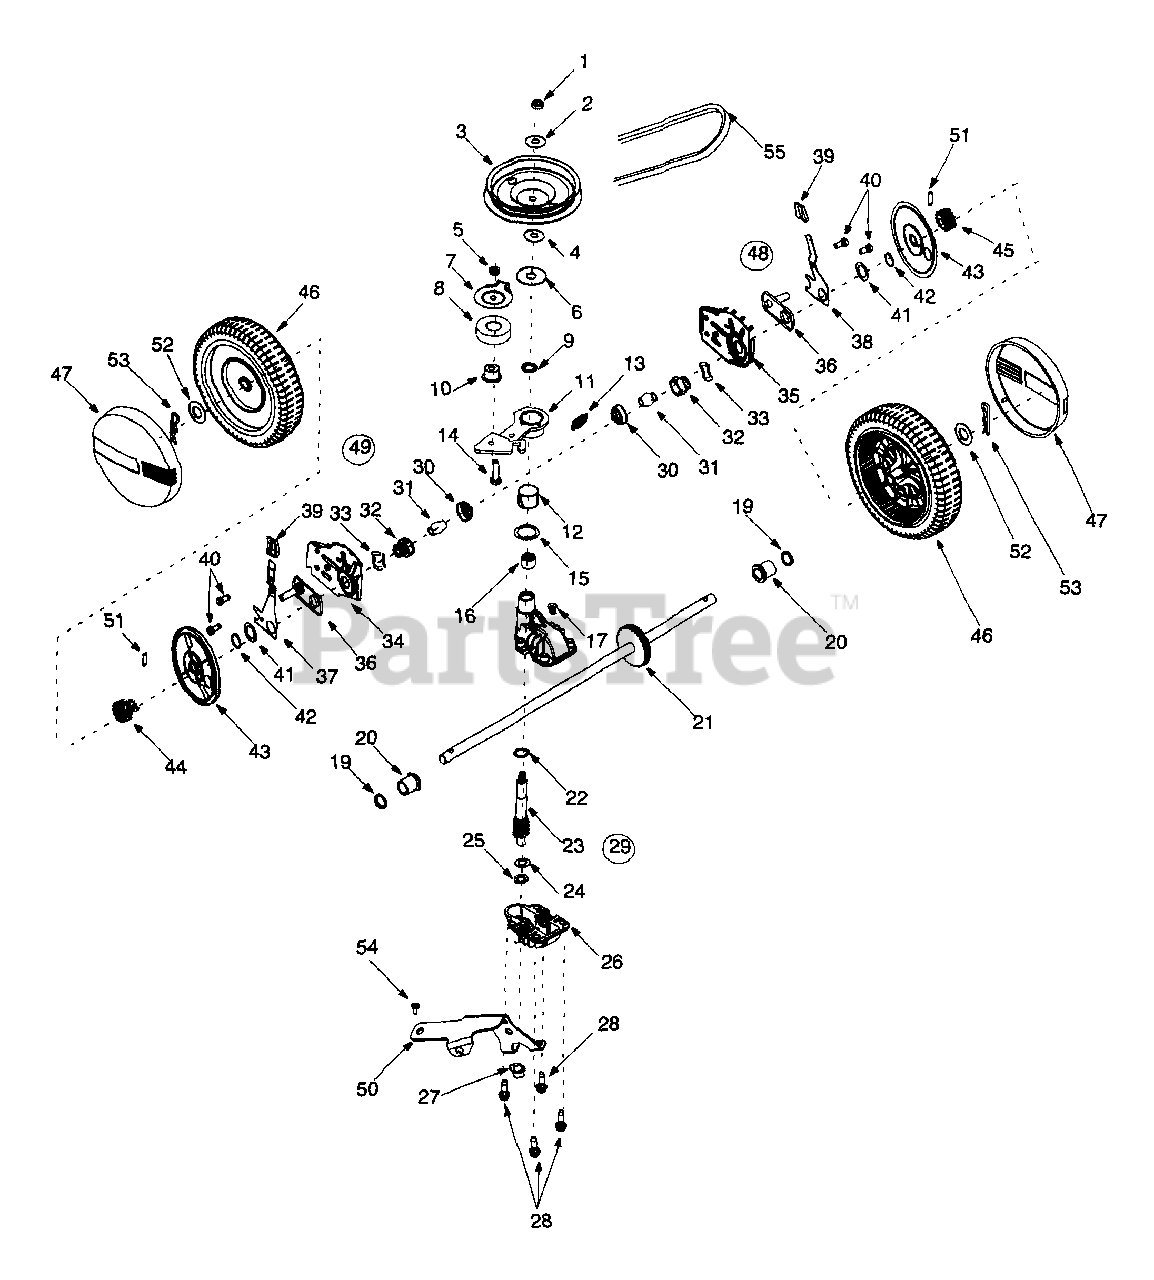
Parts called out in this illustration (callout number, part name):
1	Hex Jam Nut 5/16-24
2	Bell Washer .325 x .930 x .045
3	Pulley, 3.82 x .313 x .68
4	Bell Washer .325 x .930 x .045
5	Lock Nut 1/4-28
6	Flat Washer .442 x 1.38 x .060
7	Belt Keeper
8	Ball Bearing
9	Oil Seal
10	Flange Spacer
11	Idler Bracket Assembly
12	Bearing Sleeve
13	Flat Washer .504 x .700 x .030
14	Hex Cap Screw 1/4-28 x 1.00
15	Flat Washer .865 x 1.145 x .030
16	Needle Bearing .438 x .625 x .500
17	Plug 1/4 x .437
19	Oil Seal .500 x .687 x .094
20	Flange Bearing
21	Output Shaft
22	Flat Washer .504 x .700 x .030
23	Pinion Shaft 10T
24	Thrust Washer .375 x .70 x .030
25	Thrust Washer .388 x .625 x .062
26	Lower Housing
27	Flange Bearing .378 x .531 x .370
28	Hex Screw w/Washer 1/4-20 x .750
29	Transmission Assembly
30	Bearing Retainer
31	Bearing Sleeve .50 I.D.
32	Bearing Support
33	Wave Washer 1.5 x 1.0 x .029
37	RH Front Lever
38	LH Front Lever
39	Knob
40	Hex Cap Screw 3/8-16 x .75
41	Washer DD 1.5" O.D.
42	Snap Ring 1.0 dia.
43	Wheel Dust Cap
44	Gear 14T RH FWD
45	Gear 147 LH FWD
46	Wheel, 8 x 2 Yellow (Link Trd.)
47	Hubcap: Yellow
48	RH Height Adj. Complete
49	LH Height Adj. Complete
50	Cable Idler Bracket
51	Dowel Pin
52	Flat Washer 1/2 x 1.00 x .063
53	Cotter Pin .08 x 1.42
54	Screw
55	Belt
